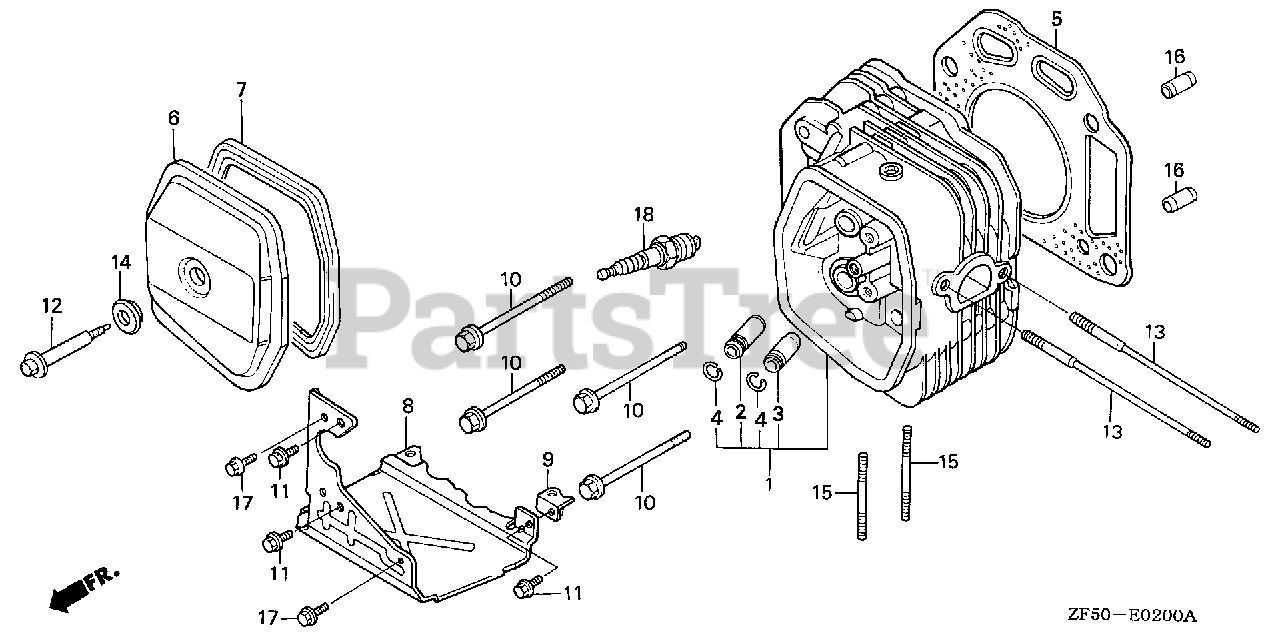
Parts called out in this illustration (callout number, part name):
1	CYLINDER HEAD
2	GUIDE, VALVE (OVER SIZE)
3	GUIDE, EX. VALVE (OVER SIZE)
4	CLIP, VALVE GUIDE
5	GASKET, CYLINDER HEAD
6	COVER, HEAD
7	GASKET, HEAD COVER
8	COVER (LOWER)
9	STAY, COVER (LOWER)
10	BOLT, FLANGE (10X85)
11	BOLT, FLANGE (6X12) (CT200)
12	BOLT, HEAD COVER
13	BOLT, STUD (8X131.5)
14	WASHER, HEAD COVER
15	BOLT, STUD (8X32)
16	PIN, DOWEL (12X20)
17	BOLT, FLANGE (6X12)
18	SPARK PLUG (BPR5ES) (NGK)
18	SPARK PLUG (W16EPR-U) (DENSO)
